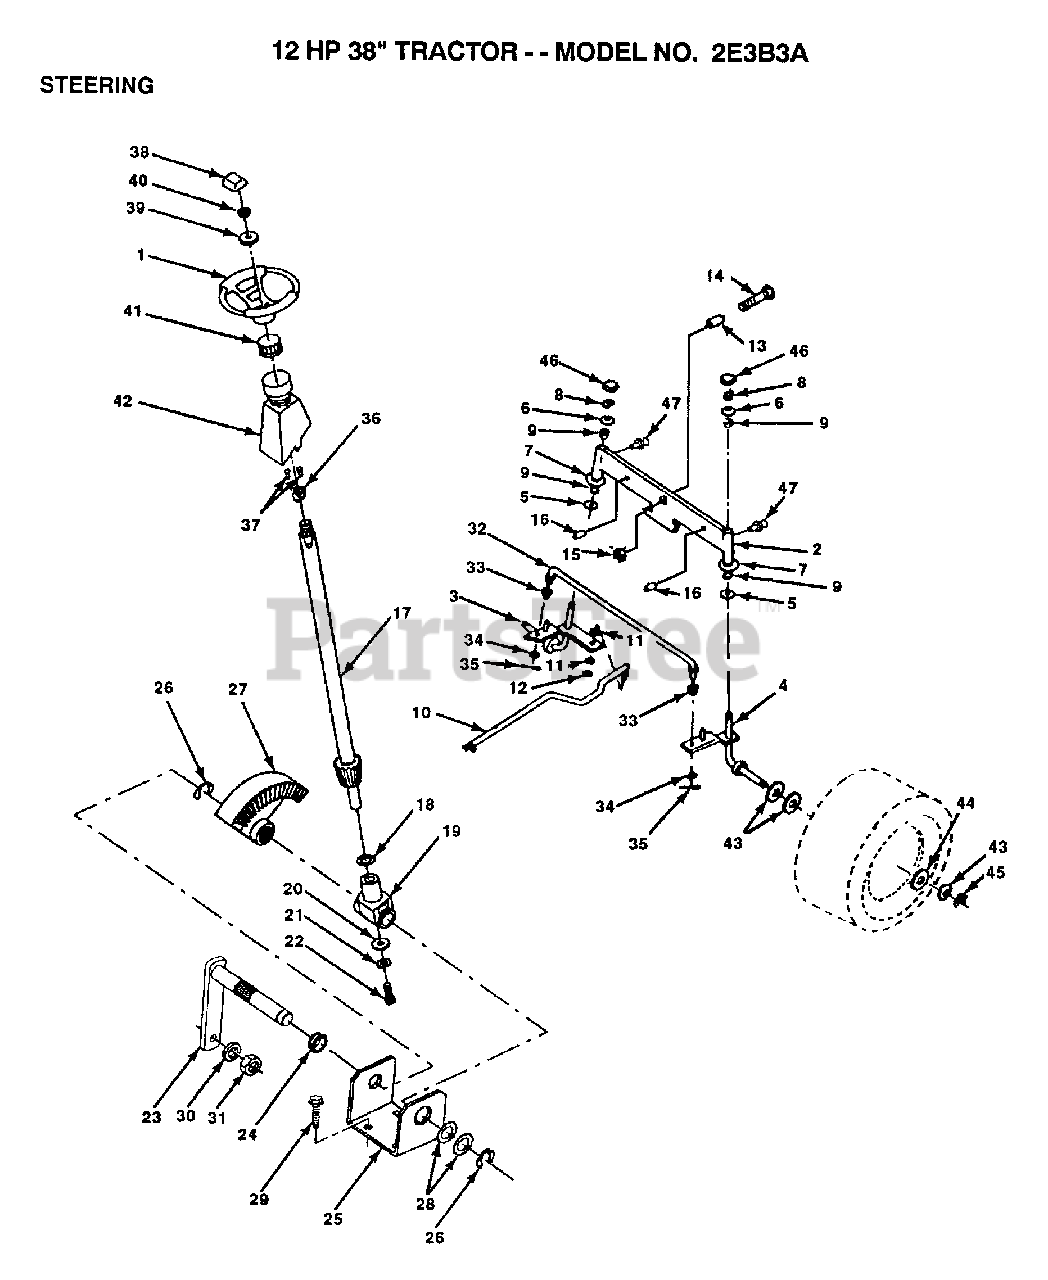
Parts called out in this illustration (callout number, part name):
3	SPINDLE LH
4	SPINDLE RH
5	WASHER .T
6	WASHER
7	WASHER
8	RING
9	COL. SRTG. BEAR.
11	LOCKWASHER
13	BEARING
14	BOLT HEX 5/8-11
15	"NUT-LOC,FLANGE LT"
16	AXLE PIN
17	SHAFT ASM
18	THRUST WASHER
19	SUPPORT.SHAFT
21	LOCKWASHER
22	"SCREW,SPECIAL"
24	NYLINER T
25	"BRKT,STEERING"
26	RING
28	WASHER .T
29	SCREW
30	LOCKWASHER
32	TIE ROD
33	BUSHING.DRAGLINK
34	WASHER
35	COTTER PIN
38	ST WHL INSERT CAP
39	WASHER T
40	GRIPCO NUT
41	ADAPTER-WHEEL LT
42	"TUBE, STR SHAFT"
43	WASHER
44	WASHER
45	RING
46	CAP
47	ZERK M
